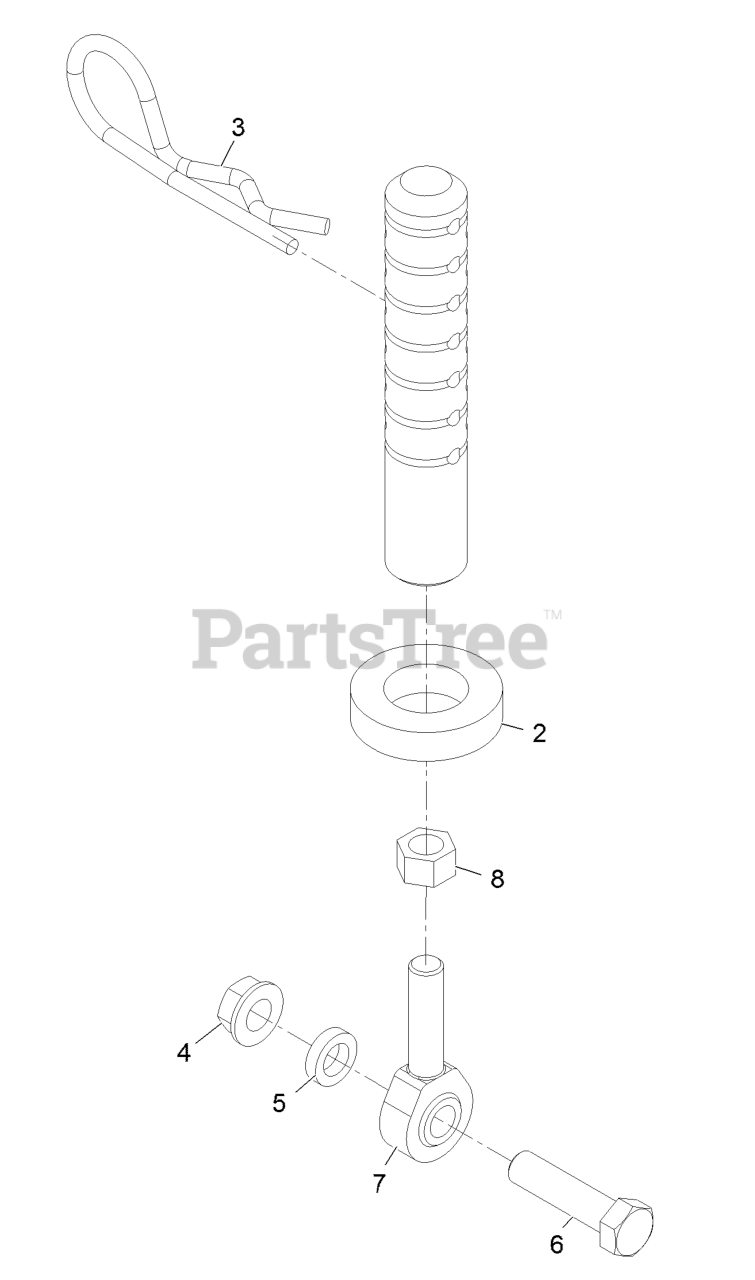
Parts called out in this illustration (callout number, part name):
2	SPACER-DECK SUPPORT
3	PIN-CUT HEIGHT
4	NUT-HHF, WHIZ
5	SPACER-IDLER
6	SCREW-HH
7	BALLJOINT
8	NUT-HJ
